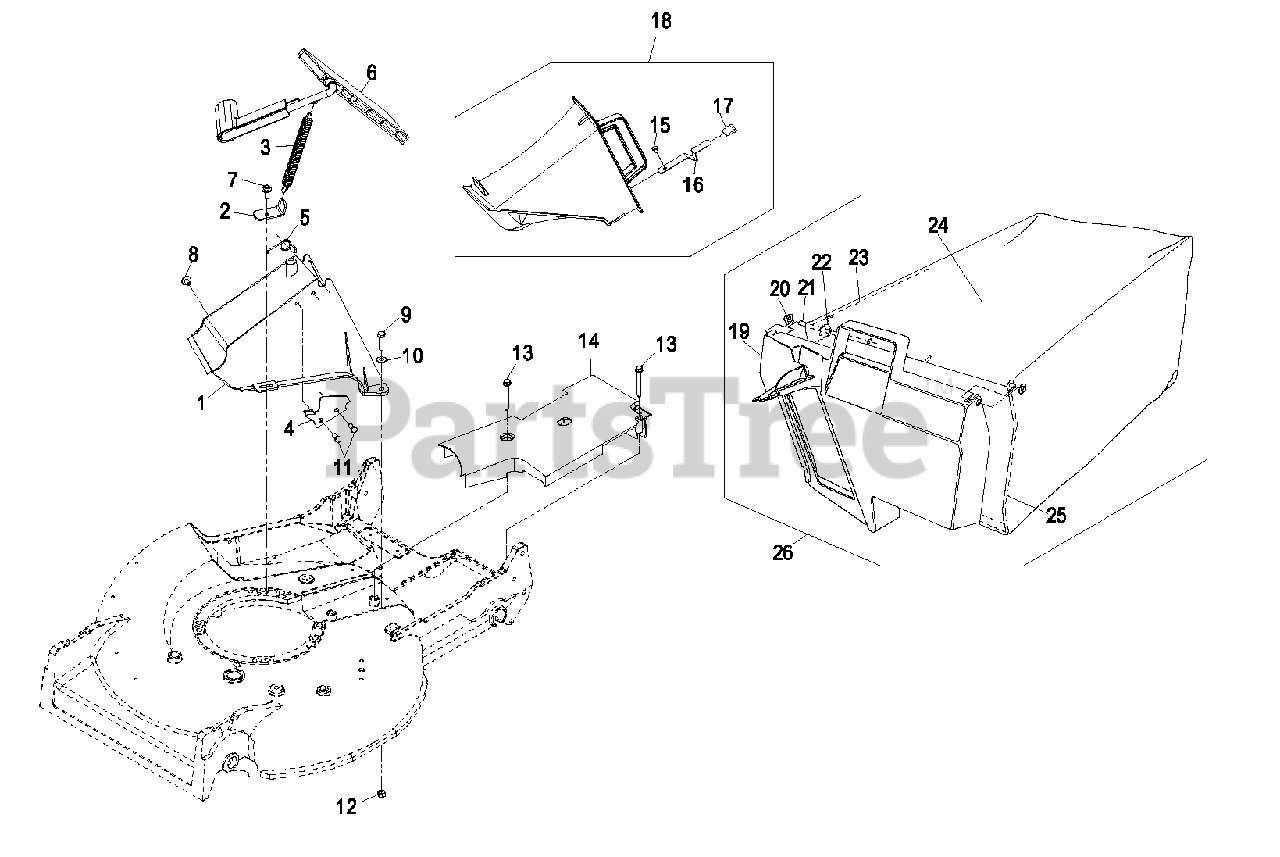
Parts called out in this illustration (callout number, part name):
1	TUNNEL-DISCHARGE
2	BRACKET-SPRING
3	SPRING-DOOR
4	LATCH-PLATE
5	RETAINER-DOOR
6	DISCHARGE DOOR ASM
7	SCREW-HWH
8	SCREW AND WASHER ASM
9	SCREW-HH
10	WASHER-FLAT
11	SCREW-PLASTITE
12	NUT-LOCK, NI
13	SCREW-HWH
14	COVER-BELT
15	RIVET-HEAD, FLAT
16	LATCH-PLUG, DISCHARGE
17	GRIP-LATCH
18	DISCHARGE PLUG ASM
20	NUT-PUSH
21	HINGE-DOOR, BAG
24	BAG, GRASS METRO21
25	FRAME-BAG
26	ASM,GRASS BAG
